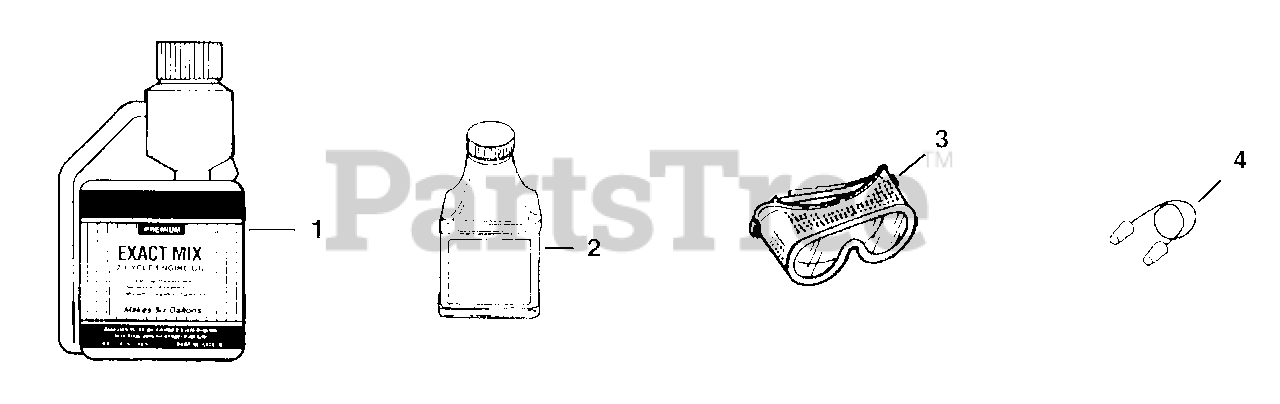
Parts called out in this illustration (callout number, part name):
1	EXACT MIX (TM) (16 oz.)
2	EXACT MIX (TM) (2.6 oz.)
4	EAR PLUGS
5	DECAL KIT - GH24
